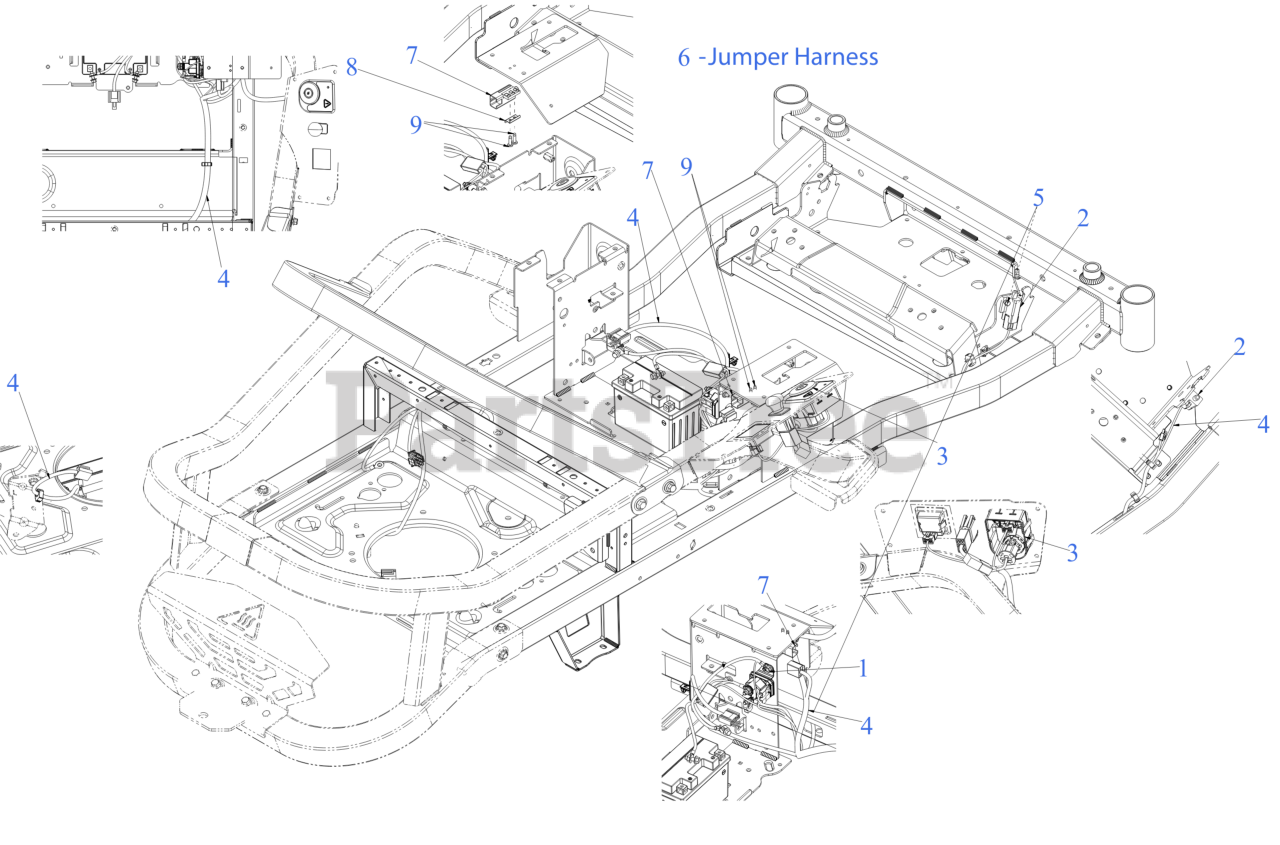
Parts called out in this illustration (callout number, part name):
1	SCREW 1/4-20X.625
2	INTERLOCK SWITCH (NO/NC)
3	IGNITION MODULE SWITCH (RMC ELC PTO WHTE)
4	MAIN HARNESS (RMC/LIGHT/H1)
4	12V SOLENOID
5	SHOULDER SCREW
6	JUMPER HARNESS (KH-ZT)
7	SCREW MOUNT SWITCH NO/NC
8	PLATE-SWITCH
9	SCREW #10-24X11/16 T-25
